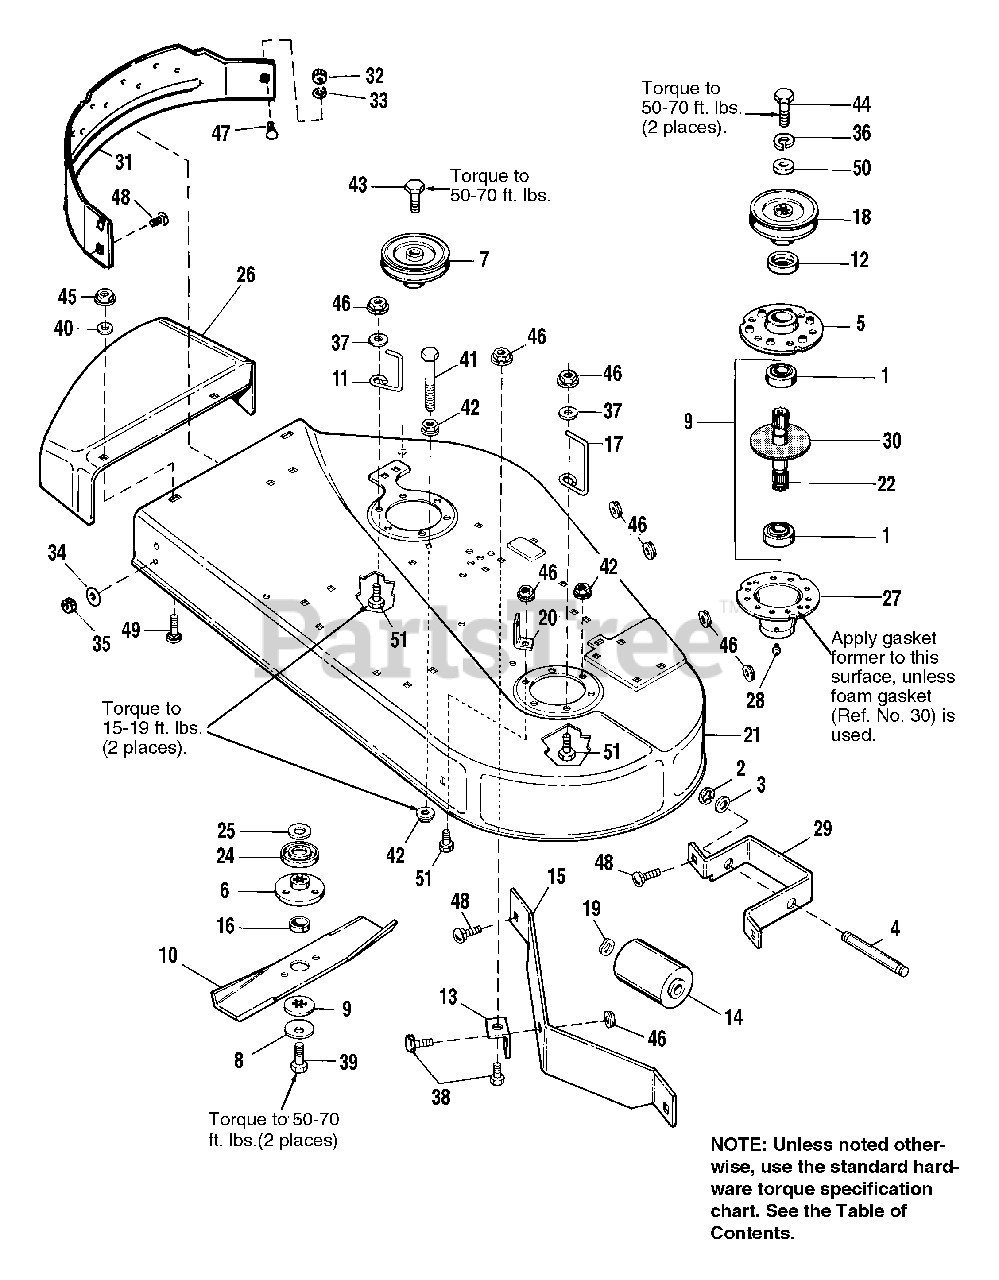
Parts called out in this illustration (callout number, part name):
2	E-RING
3	WASHER, Nylon
4	SHAFT, Roller, Center
5	ARBOR HOUSING, Top
6	ADAPTOR, Blade
7	PULLEY ASSY.
8	WASHER, Cup
9	WASHER, Spline
12	SHIELD, Bearing Upper, Arbor
13	BRACKET, Mower
15	BAFFLE
16	COLLAR, Arbor
18	PULLEY ASSY.
19	WASHER, Wave
20	BRACKET, Lift
21	HOUSING, 36", Orange
21	HOUSING, 36", Black,
22	SHAFT, Arbor
24	SHIELD, Grass
25	WASHER, Shim
26	DEFLECTOR, Orange
26	DEFLECTOR, Black
27	ARBOR HOUSING ASSY., Bottom
28	GREASE FITTING
29	BRACKET, Center, Roller
30	GASKET, Foam
31	BAFFLE, Mulching
32	NUT, Hex, 1/4-20
33	LOCKWASHER, 1/4
34	LOCKWASHER, 5/16
35	NUT, Hex, 5/16-18
36	LOCKWASHER, 7/16
37	WASHER, 11/32
38	CAPSCREW, Hex Hd., 5/16-18 x 3/4
39	CAPSCREW, Hex Hd., 7/16-14 x 1
40	WASHER, 13/32
41	CAPSCREW, Hex Hd., 5/16-18 x 3-1/2
42	NUT, Hex , Flange, Whizlock, 5/16-18
43	CAPSCREW, Hex Hd., 7/16-14 x 2-3/4
44	CAPSCREW, Hex Hd., 7/16-14 x 3-1/2
45	NUT, Hex, Flange, Whizlock, 3/8-16
46	NUT, Hex, Flange, Whizlock, 5/16-18
47	CARRIAGE BOLT, 1/4-20 x 3/4
48	CARRIAGE BOLT, 5/16-18 x 3/4
49	CARRIAGE BOLT, 3/8-16 x 3/4
50	WASHER, 29/64 x 1-1/4 x 1/4
51	SCREW, Hex, Wash. Hd., Taptite, 5/16-18 x 1
